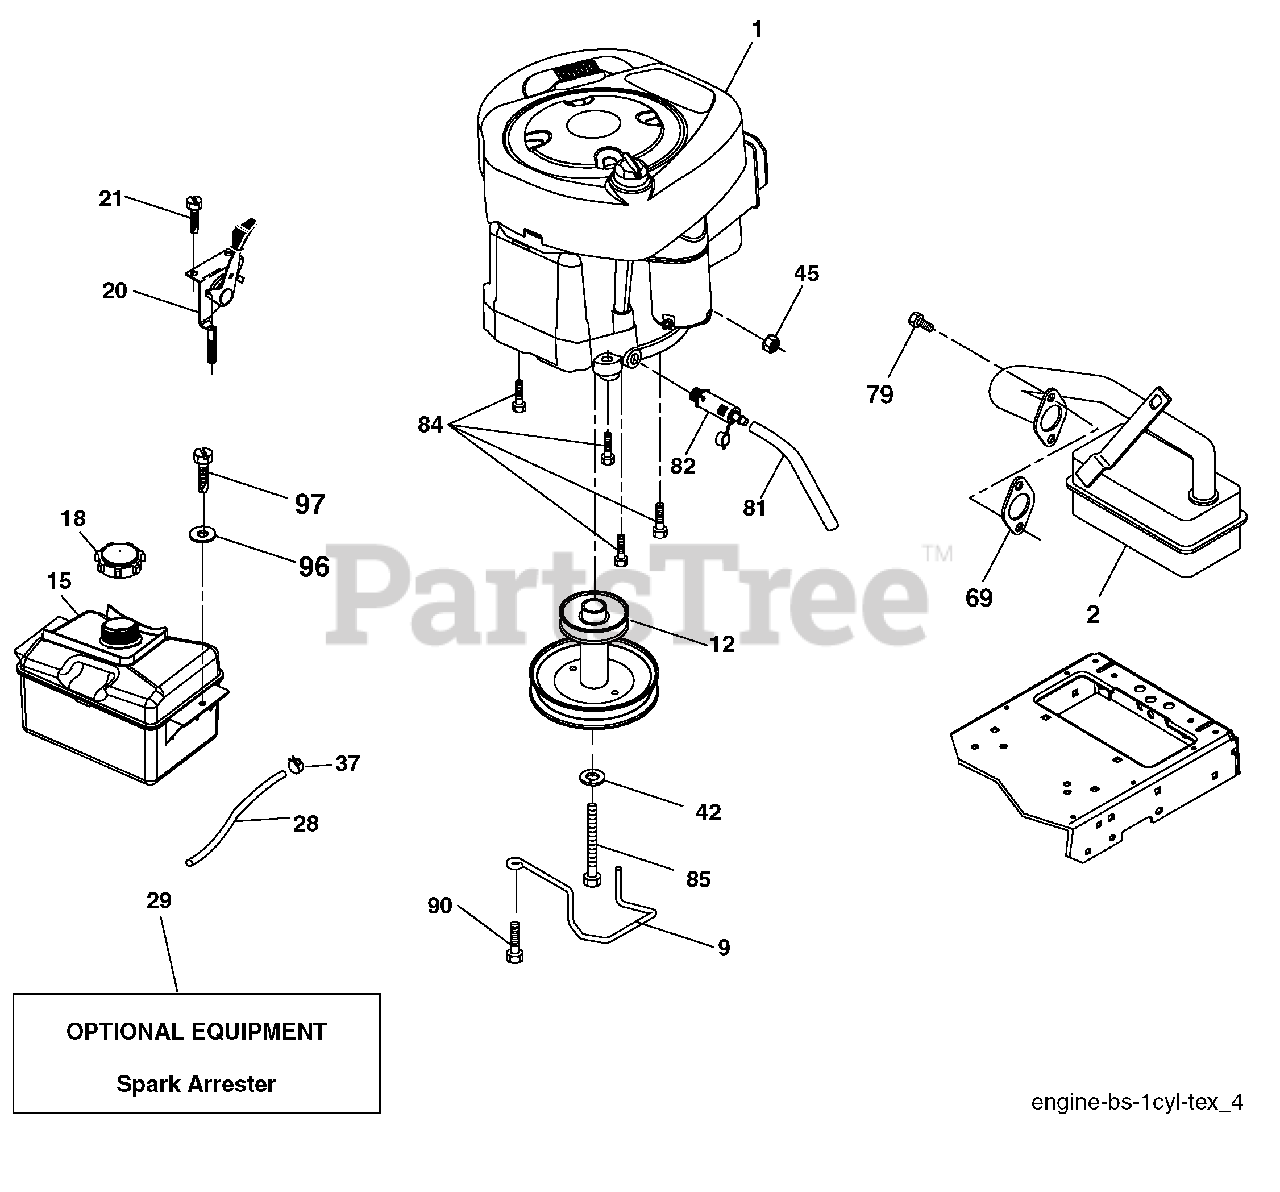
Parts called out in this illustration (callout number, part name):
2	Muffler
9	Keeper Belt Engine
12	Pulley Engine
15	Tank Fuel 1.50
18	Cap Asm
20	Control Throttle/Choke
21	Screw 10 x 3/4 Single Lead-Hex
28	Fuel Line
29	Spark Arrester Kit
37	Clamp Hose
42	Washer Lock 7/16
45	Nut Keps Hex 1/4-20 unc
69	Gasket
79	Screw Socket Hd 5/16-18 x .75
81	Tube Drain Oil Easy
82	Plug Drain Oil
84	Screw 3/8-16 x 1-1/4
85	Bolt Hex 7/16-20 x 4 x Gr. 5-1.5
90	Screw 3/8-16 x 1.0
96	Washer 9/32 x 7/8 x 16
97	Screw Hex Thdrol 1/4-20 x 3/4
